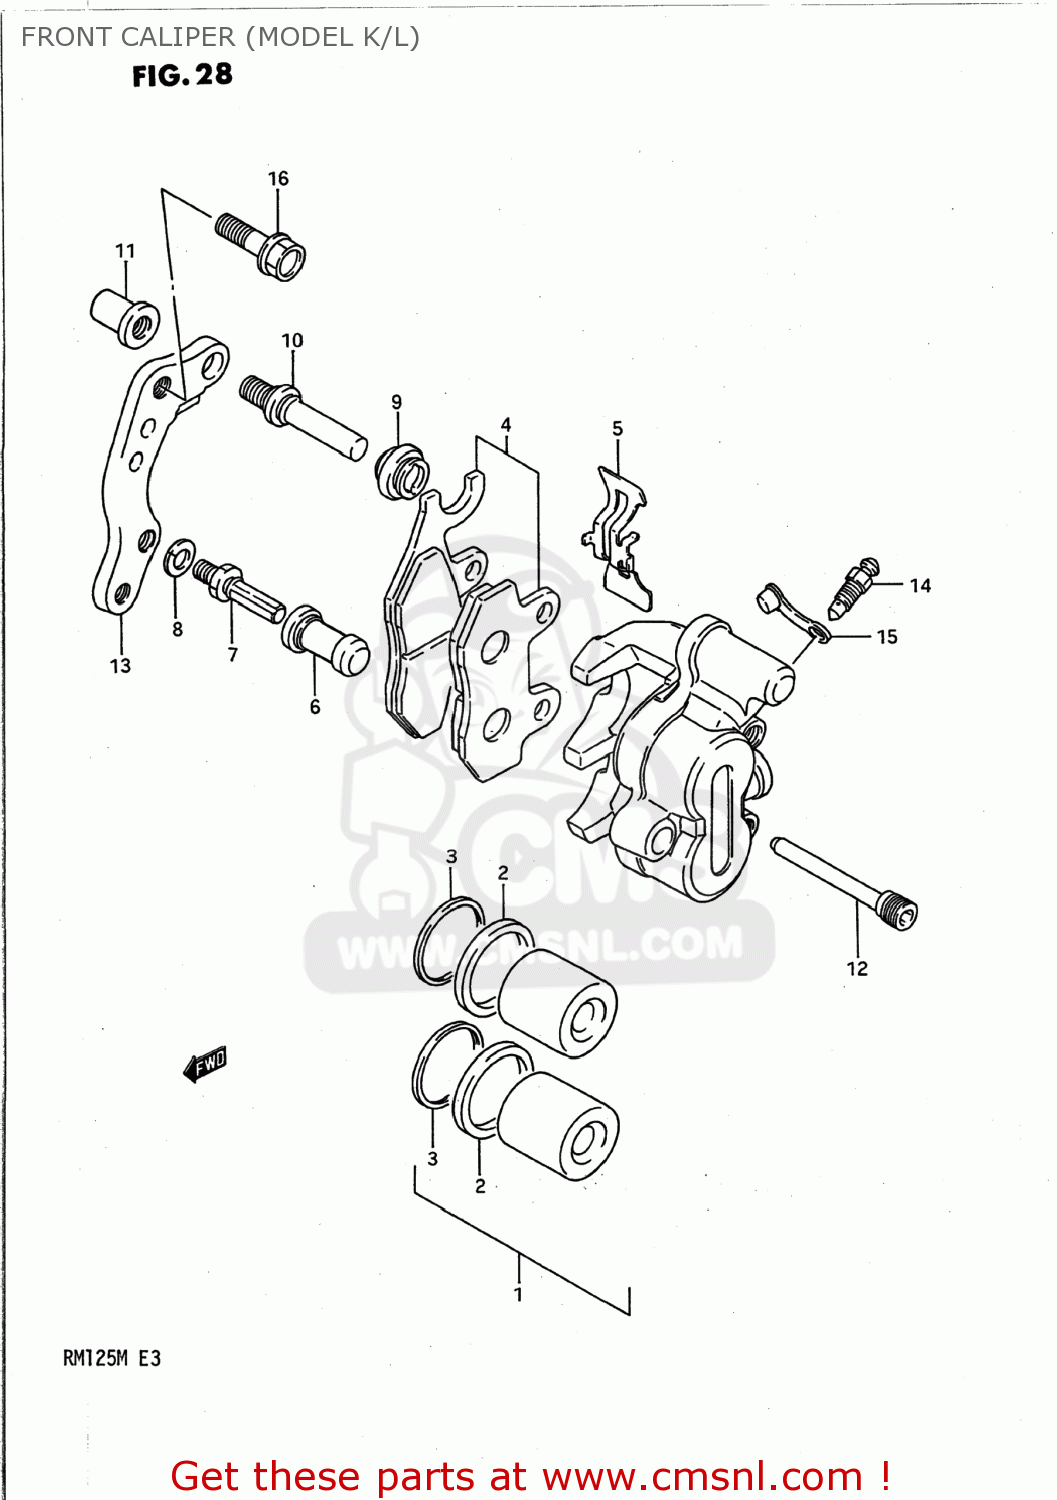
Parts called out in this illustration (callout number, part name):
1	PISTON SET
2	SEAL,PISTON
3	SEAL,DUST
4	PAD SET (NAS)
5	SPRING
6	BOOT
7	BOLT,PIN
8	WASHER,WAVE
9	BOOT
10	PIN,SLIDE
11	NUT
12	PIN,HOLDER
13	BRACKET
14	BLEEDER
15	CAP,BLEEDER
16	BOLT
